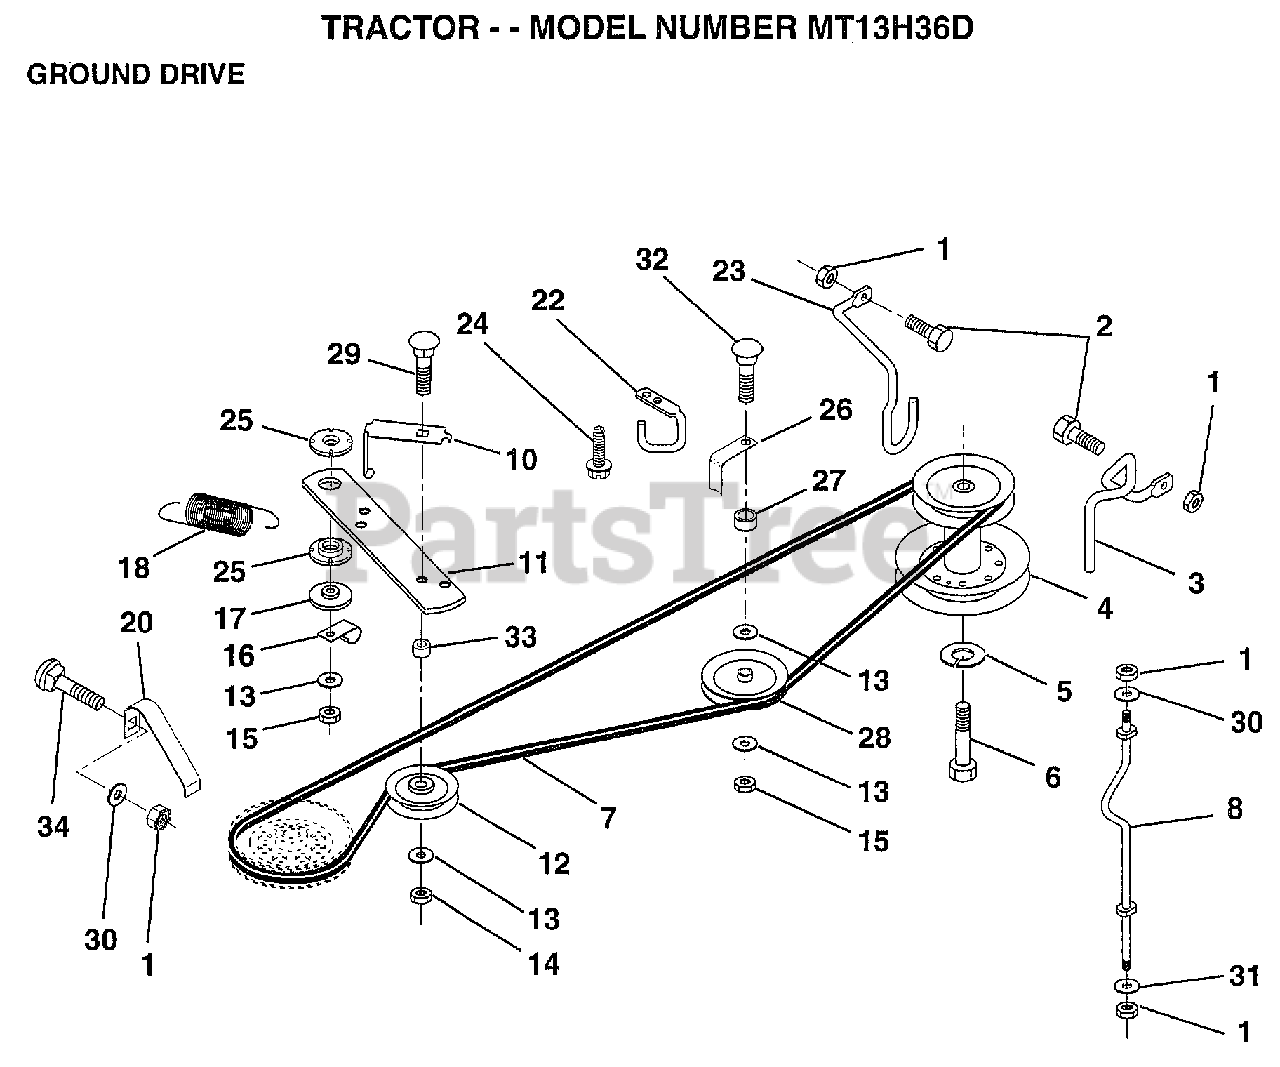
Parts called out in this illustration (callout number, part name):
1	PULLEY.V-GROOVE
3	TRANSAXLE HYD 0319-0500
6	BOLT
7	STRAP.TORQUE.HYD
9	SPRING.BRAKE.RETU
10	WASHER
11	SQUARE KEY
13	FAN.HYDRO.6FANS
14	"LOCKNUT,1/2-20UNF"
16	SUPPORT.HDLE.SHFT
17	LINK.SHIFT.HYD.LR
21	LEVER.SHIFT.TRANS
23	KNOB.DUCKHEAD.1/2
24	ROD.SHIFTER.HYD.
25	PIN COTTER 1/8
27	"LINE FUEL HYD 4"""
28	SPRING.TORSION.LR
30	RETAINER M
31	SPACER SPLIT
32	WASHER
35	E-RING LT
36	SCREW
37	NUT
38	BOLT.HEX.FLGHD
39	WASHER
40	BOLT.HEX.5/16-1.5
41	WASHER
42	PIN.PIVOT.SHIFT.
43	WASHER
44	SHAFT.PIVOT.LR.
48	ACTUATOR.BYPASS
49	WASHER M
